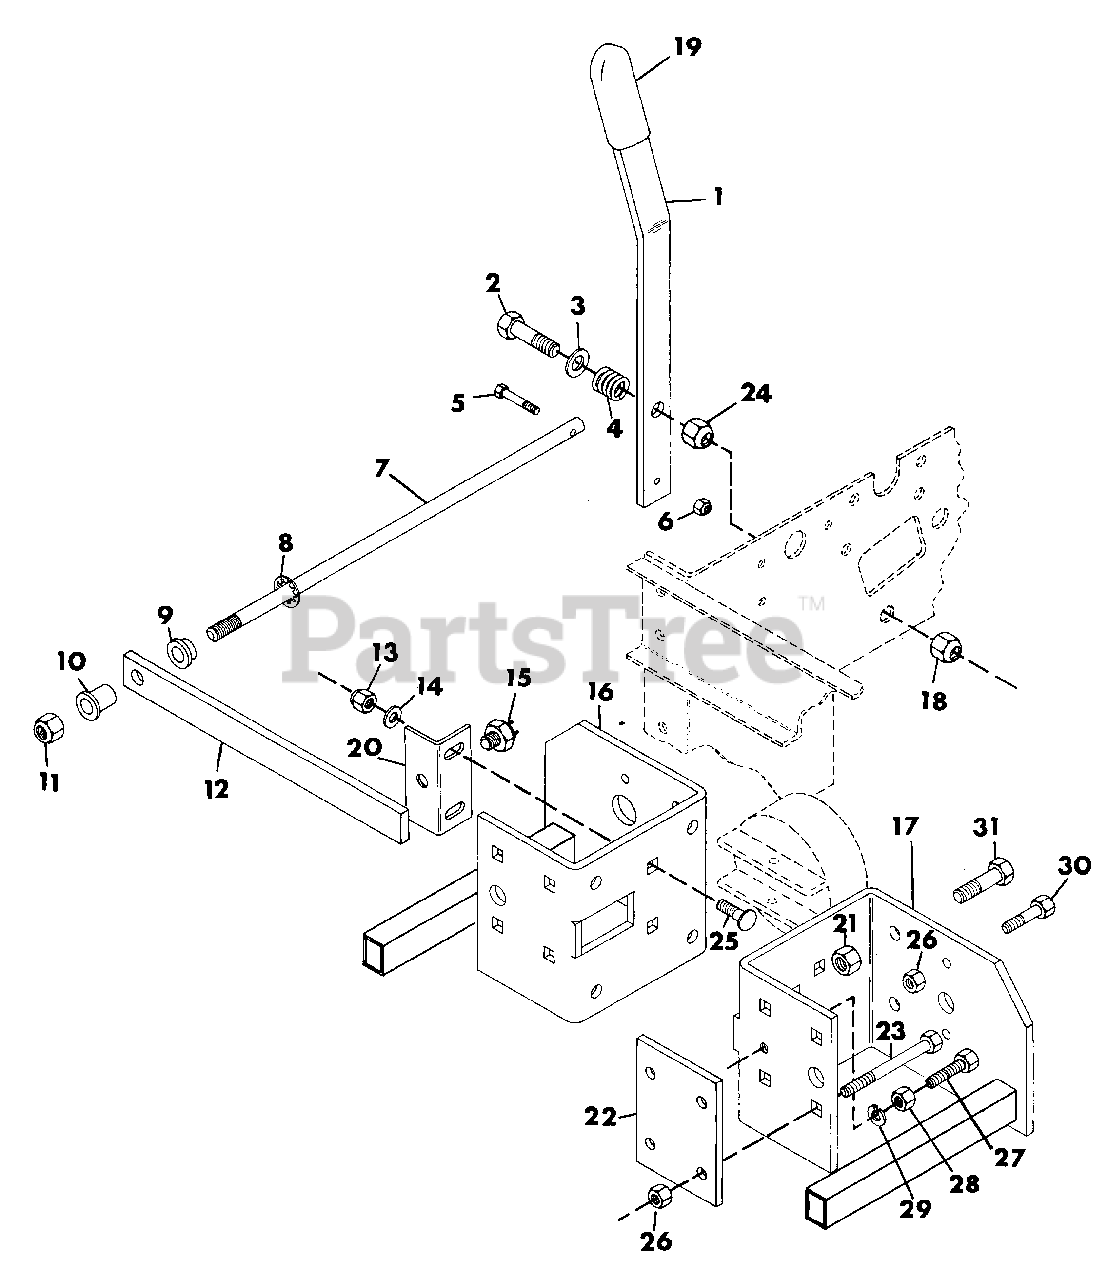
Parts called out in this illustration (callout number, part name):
1	LEVER, PTO
2	BOLT, HEX 1/2-13X2.500
3	WASHER, FLAT .531X1.062X.095
4	SPRING, COMPRESSION 1.00X.78X338 LB/IN
5	BOLT, HEX 1/4-20X1.25
6	NUT, LOCK 1/4-20
7	ROD, PTO
8	RING, RETAINING
9	BUSHING, .513X.750X.375
10	BUSHING, FWD-REV SLIDE ROD
11	NUT, LOCK 1/2-20
12	SPRING, FWD-REV CLUTCH
13	NUT, LOCK 5/16-18
14	WASHER, FLAT .344X.688X.065
15	SWITCH, NEUTRAL START
16	WELDMENT, R.H. MOWER BRACKET
17	WELDMENT, L.H. MOWER BRACKET
18	NUT, HEX 1/2-13
19	GRIP, HANDLE
20	BRACKET, INTERLOCK SWITCH
21	NUT, RIM
22	PLATE, ATTACHMENT CLAMP
23	BOLT, HEX 3/8-16X3.25
24	NUT, JAM 1/2-13 HEX
25	BOLT 5/16-18X.875 RD HD SQ NK
26	NUT, LOCK 3/8-16
27	BOLT, HEX 3/8-16X2.00
28	NUT, JAM 3/8-16 HEX
29	WASHER, LOCK 3/8 REG.
30	BOLT, HEX 3/8-16X1.00
31	BOLT, HEX 1/2-20X1.50
